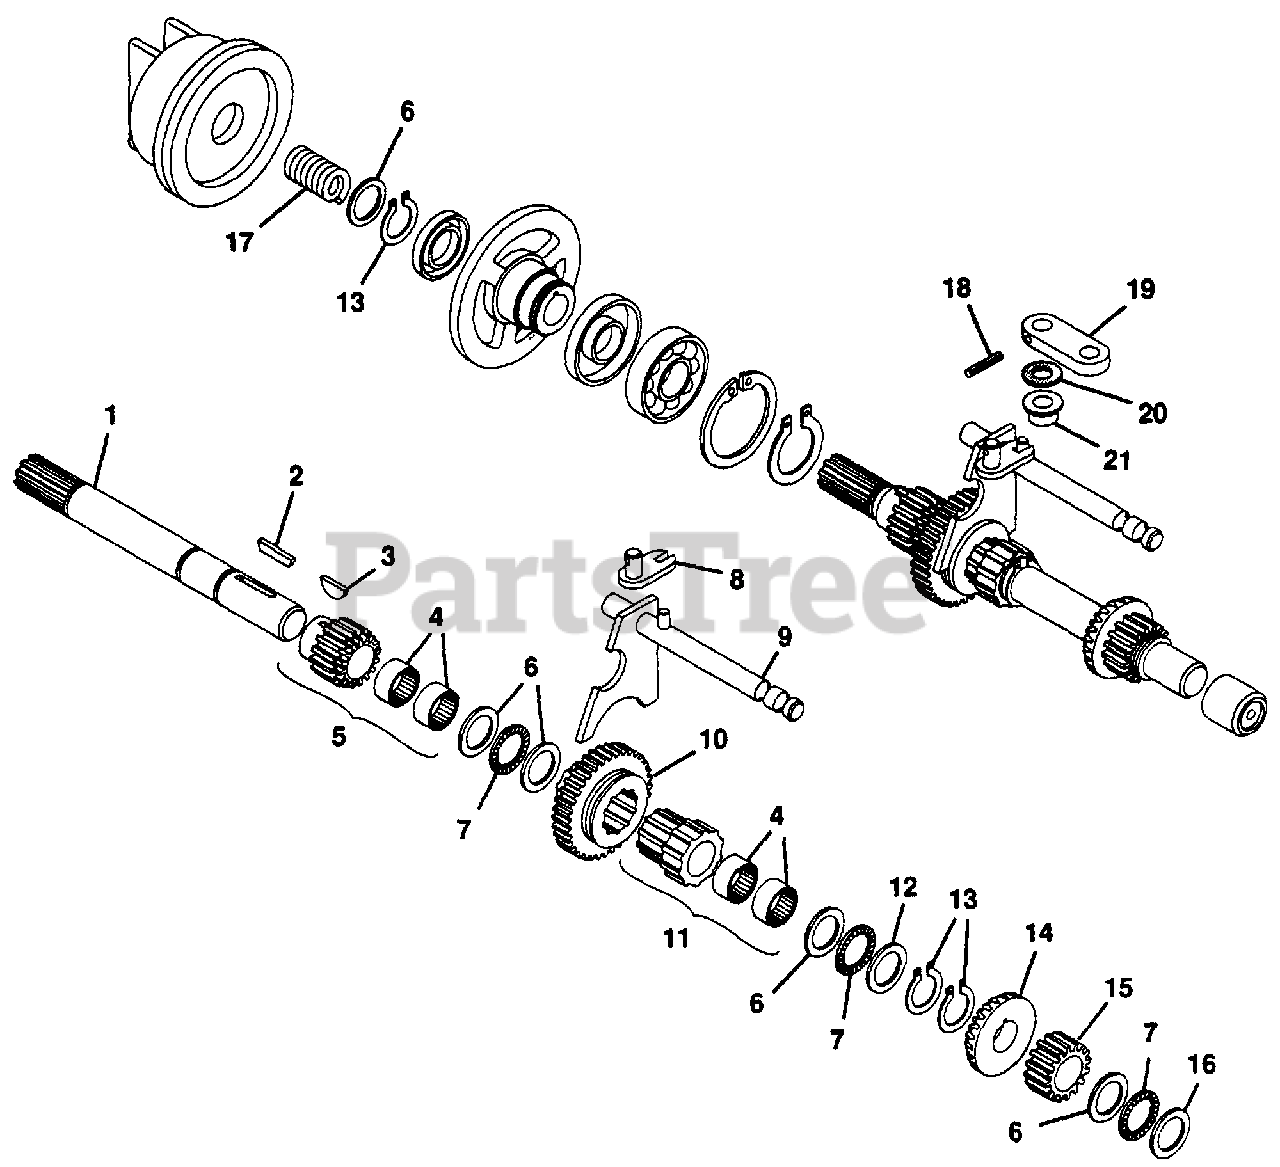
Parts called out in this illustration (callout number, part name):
1	SHAFT, FWD CLUTCH
2	KEY, WOODRUFF .188X1.25 HRD #19
3	KEY, WOODRUFF .188X.625 HRD #61
4	BEARING, NEEDLE .75X1X.50
5	GEAR AND BEARING ASSEMBLY
6	RACE, BRG THRUST .752X1.240X.030
7	BEARING, THRUST .752X1.240X.078
8	WELDMENT, SHIFTER
9	WELDMENT, SHIFT RAIL
10	GEAR, SPUR
11	GEAR AND BEARING ASSEMBLY
12	RACE, .060 BEARING THRUST
13	RING, RETAINING .750 SHAFT
14	GEAR, BEVEL
15	GEAR, 10 DP 16 TEETH X.750 STD.
16	RACE, THRUST .752X1.240X.095
17	SPRING, COMP. 1.0X.80X36 LB/IN
18	PIN, SPRING .188X1.00
19	ARM, SHIFTER
20	WASHER, FELT
21	BUSHING, 2-SPEED
